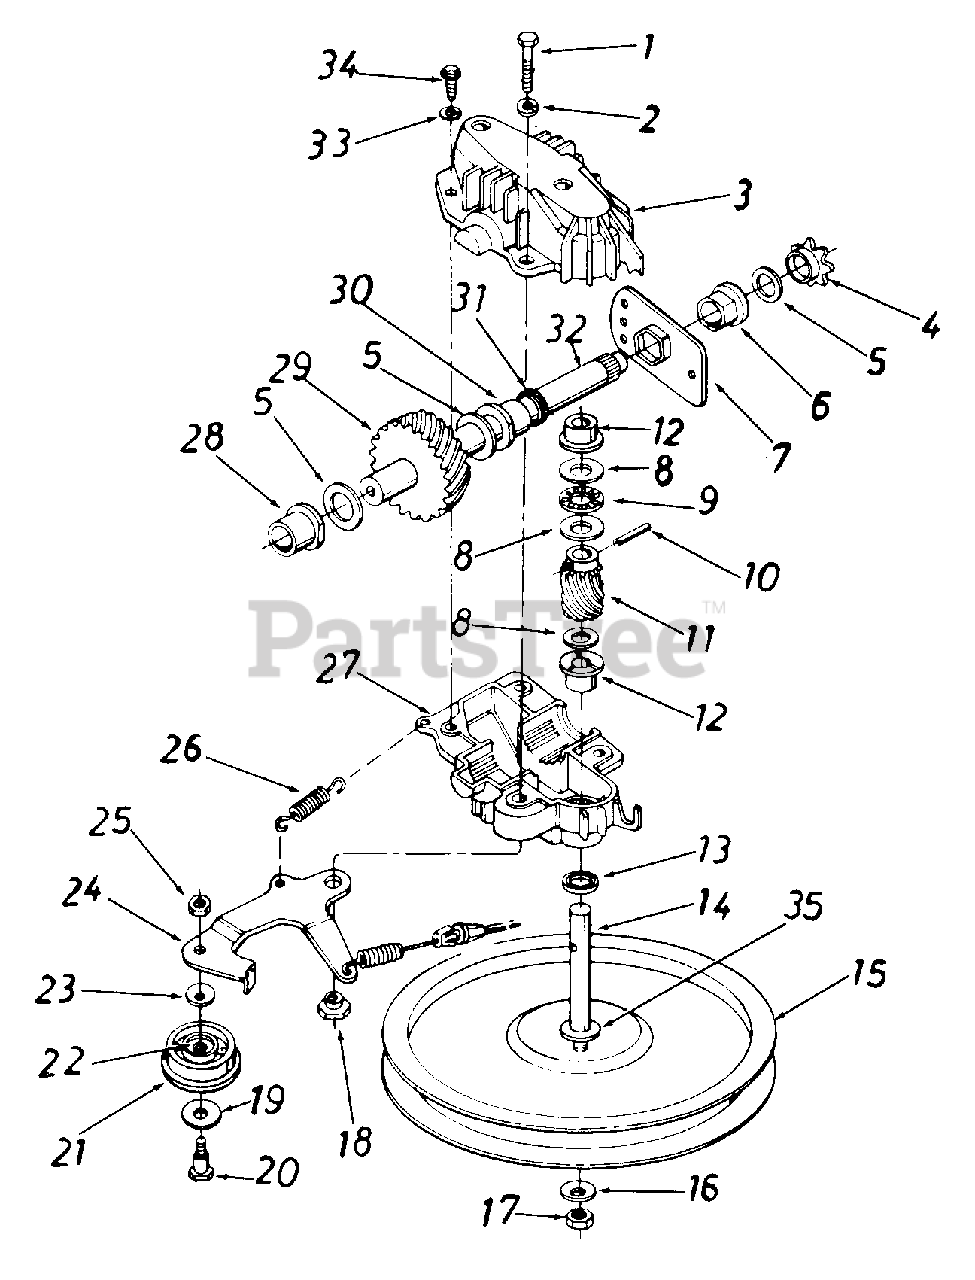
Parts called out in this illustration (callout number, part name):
1	Hex Bolt 1/4-20 x 1.25" Lg.
2	L-Wash. 1/4" I.D.
3	Upper Transmission Hsg. Half
4	#48 Sprocket 7 Tooth x 1/2 Pitch
5	Fl-Wash. 5/8" I.D. x .030
6	Hex Flange Brg. .631" I.D.
7	Hex Bearing Cup
8	Thrust Wash. .382" I.D. x .70" O.D.
9	Thrust Bearing .375" I.D. x .812" O.D.
10	Spring Pin Spir. 1/8" x .62" Heavy
11	11 Tooth Helical Gear
12	Flange Bearing
13	Oil Seal
14	Pulley-Transmission Shaft .375 O.D.
15	Fl-Pulley 5.06" O.D.
16	Bell-Wash. .265" I.D. x .75"
17	Hex Lock Nut 1/4-28 LH Thd
18	Shld. Spacer .375" Dia. x .170
19	Fl-Wash. .390" I.D. x 1.0"
20	Shld. Bolt .375" Dia. x .40"
21	Fl-Idler Plastic 1.50" Dia. x 48
22	Needle Brg. .375" x .31
23	Bell-Wash. .265" I.D. x .75"
24	Idler Brk't. Ass'y.
25	Hex Patch L-Nut 1/4-28 Thd.
26	Extension Spring 1.12" Lg.
27	Lower Transmission Hsg. Half
28	Flange Bearing .566 Dia.
29	33 Tooth Helical Gear
30	Flange Bearing .629 Dia.
31	Oil Seal .625 Dia.
32	Gear Sprocket Shaft
33	L-Wash. #10
34	Hex B-Tap Scr. #10 x .62"
35	Hex Washer .26" x .88"
